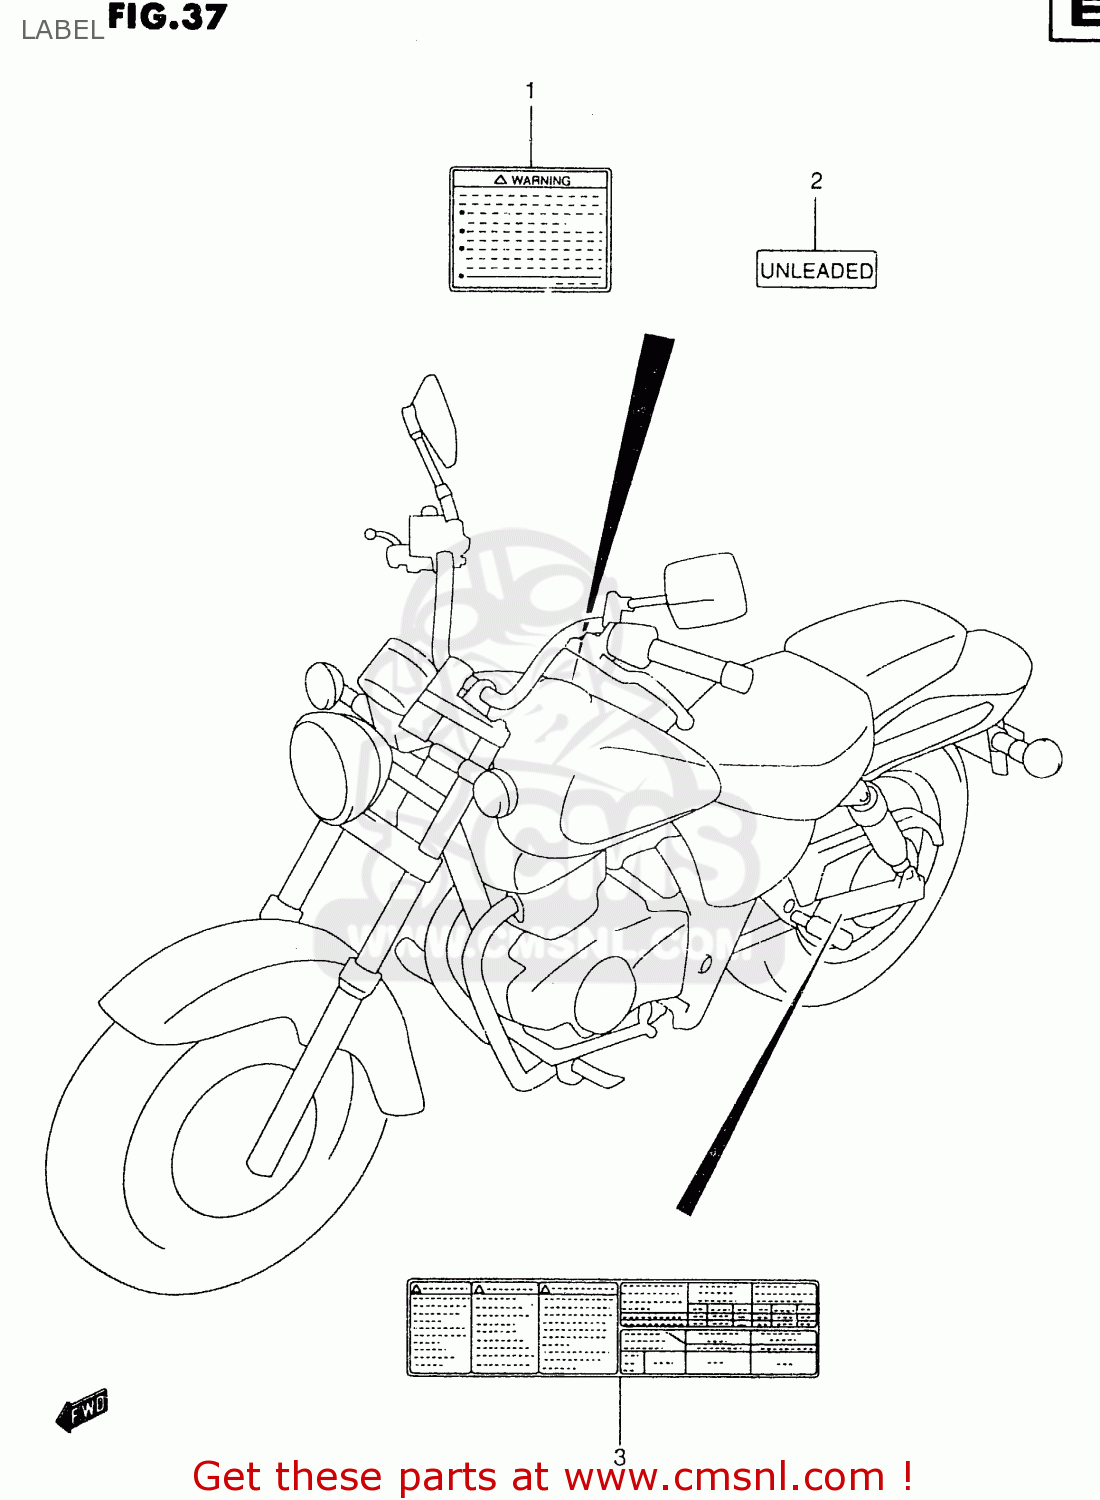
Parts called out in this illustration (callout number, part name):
1	LABEL,WARNING
2	LABEL,CAUTION
3	LABEL,TIRE INFORMATION
